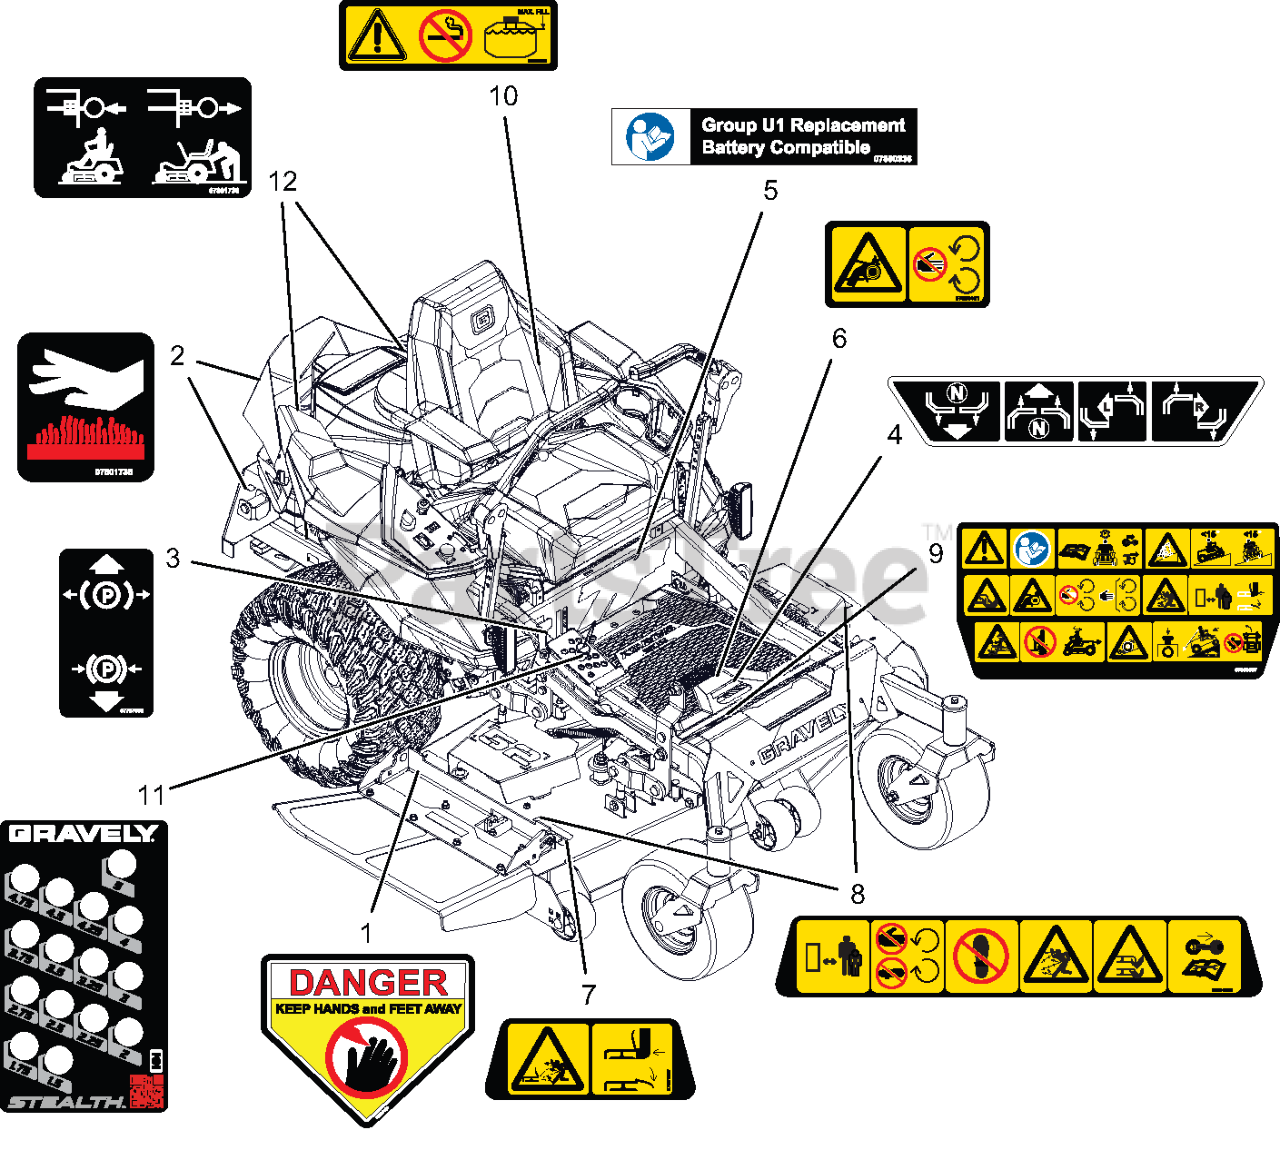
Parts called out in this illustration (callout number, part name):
1	DECAL, DANGER
2	DECAL,SAFETY HOT SURFACE
3	DECAL, PARKING BRAKE LEVER
4	DECAL- INSTRUCTIONAL-STEERING
5	DECAL, U1 BATTERY REPLACEMENT
6	DECAL, SAFETY - GUARDING
7	DECAL- SAFETY - DECK GUARDING
8	DECAL- SAFETY - MOWER DECK
9	DECAL, MAIN SAFETY
10	DECAL, FUEL WARNING
11	DECAL- HD STEALTH HOC
12	DECAL,TRANSAXLE DISCONNECT
